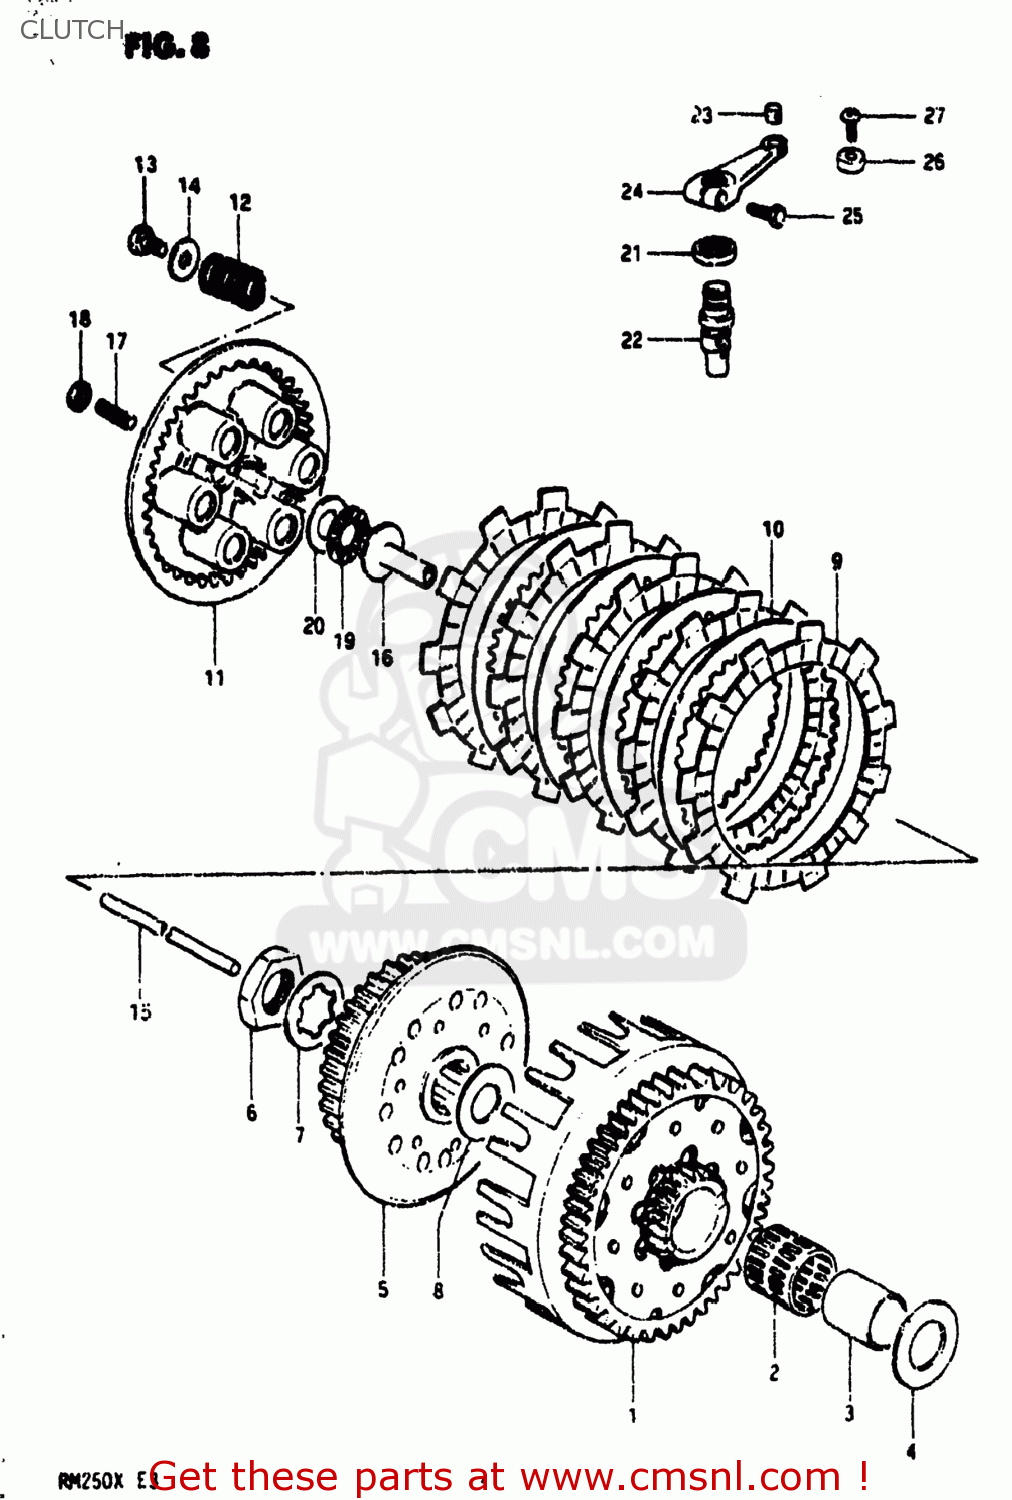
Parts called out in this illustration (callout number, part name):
1	GEAR ASSEMBLY,PRIMARY DRIVE
2	ROLLER BEARING (25X30X2
3	SPACER
4	WASHER(20X38X2)
5	HUB,CLUTCH SLEEVE
6	NUT (20MM)
7	WASHER,LOCK
8	WASHER(20X38X2)
9	PLATE,CLUTCH DRIVE (MCA)
10	PLATE,CLUTCH DRIVEN (NAS)
11	DISC,CLUTCH PRESSURE
12	SPRING
13	BOLT, UPPER
14	WASHER
15	ROD,CLUTCH PUSH
16	PIECE,CLUTCH PUSH
17	SCREW
18	NUT 6MM
19	BEARING(15X28X2)
20	WASHER
21	SEAL,OIL(12X19X5)
22	SHAFT,CLUTCH RELEASE C
23	PIECE,RELEASE ARM END
24	ARM,CLUTCH RELEASE
25	BOLT
26	GUIDE,CLUTCH CABLE
27	SCREW
